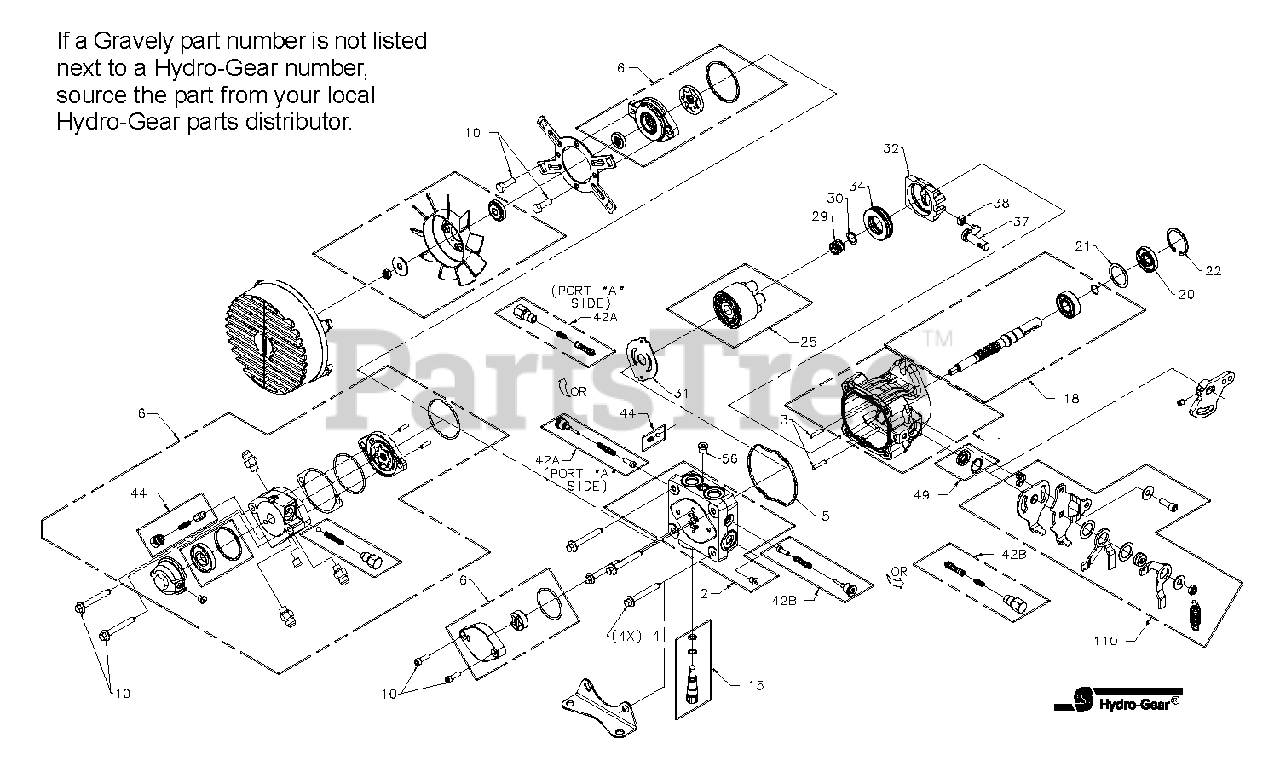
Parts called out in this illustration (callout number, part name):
1	Kit, Housing
2	Kit, End Cap w/Poppets
3	Straight Headless Pin
4	Hex, Flange Bolt M8-1.25 x 60mm
6	Kit, Chg Pump
10	Cap Screw 5/16-18
15	Kit, Bypass
18	Kit, Pump Shaft (15mm Straight Keyed, Thru)
20	Lip Seal 17 x 40 x 7 PTC
22	Retaining Ring
25	Cylinder Block Kit
29	Block Spring
30	Block Thrust Washer
31	Valve Plate
32	Swashplate
34	Ball Thrust Bearing
37	Arm, Trunnion, Tapered Square
38	Slot Guide
42	Kit, Shock Valve (200 Bar .031 Orifice)
44	Kit, Charge Relief Valve
49	Trunnion Seal - Retainer Kit
56	Plug, Straight Thread
110	Kit, Return
NS	Overhaul Seal Kit
